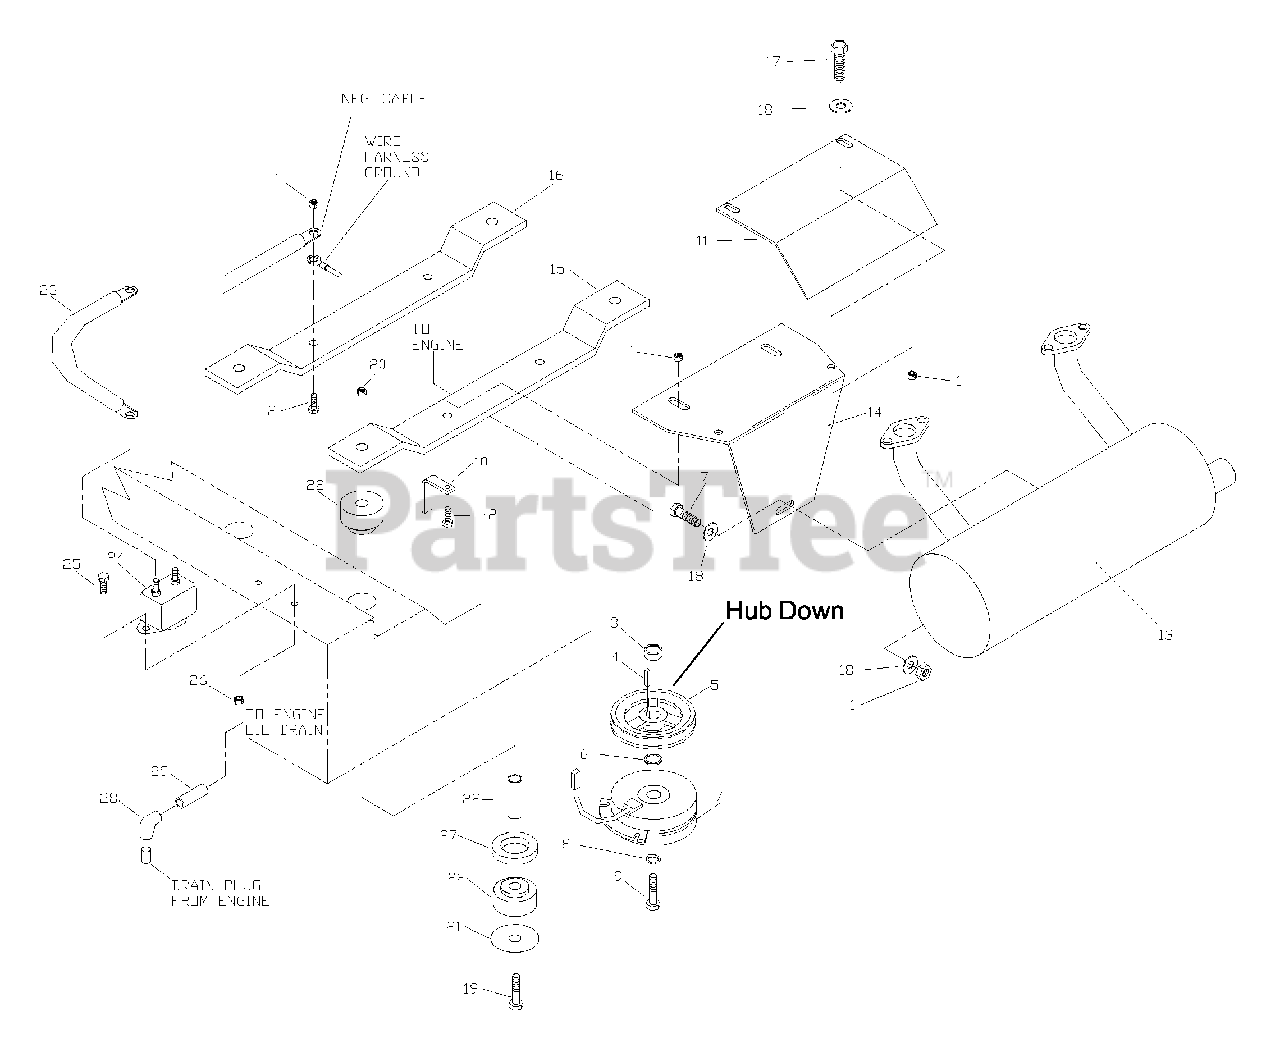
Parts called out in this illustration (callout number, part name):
1	NUT 5/16C CTR. LOCK
2	HCS 5/16C X 1.75
4	KEY 1/4SQ. X 1.0
7	ELECTRIC CLUTCH
8	7/16 LOCKWASHER
9	HCS 7/16F X 2.5
10	CLUTCH TIE DOWN
11	MUFFLER GUARD (KAW.)
12	KOHLER PIGTAIL
12	KAWASAKI PIGTAIL
13	MUFFLER, KOHLER
13	MUFFLER, KAWASAKI
14	MUFFLER BRACKET
15	ENGINE MOUNT
16	ENGINE MOUNT
17	HCS 5/16C X 3/4
18	5/16 FLAT WASHER
19	HCS 1/2C X 3.25
20	NUT 1/2C NYLOC
21	ISOLATOR WASHER
23	CABLE, POSITIVE (KAW)
24	SOLINOID (KAW)
25	HCS 1/4C X 5/8 (KAW)
26	1/4C CTR. LOCK (KAW)
27	ISOLATOR SPACER
28	ELBOW (KOHLER)
29	3/8 NPT X 1.5 PIPE (KOHLER)
40	OIL DRAIN HOSE CLAMP (KAWASAKI)
